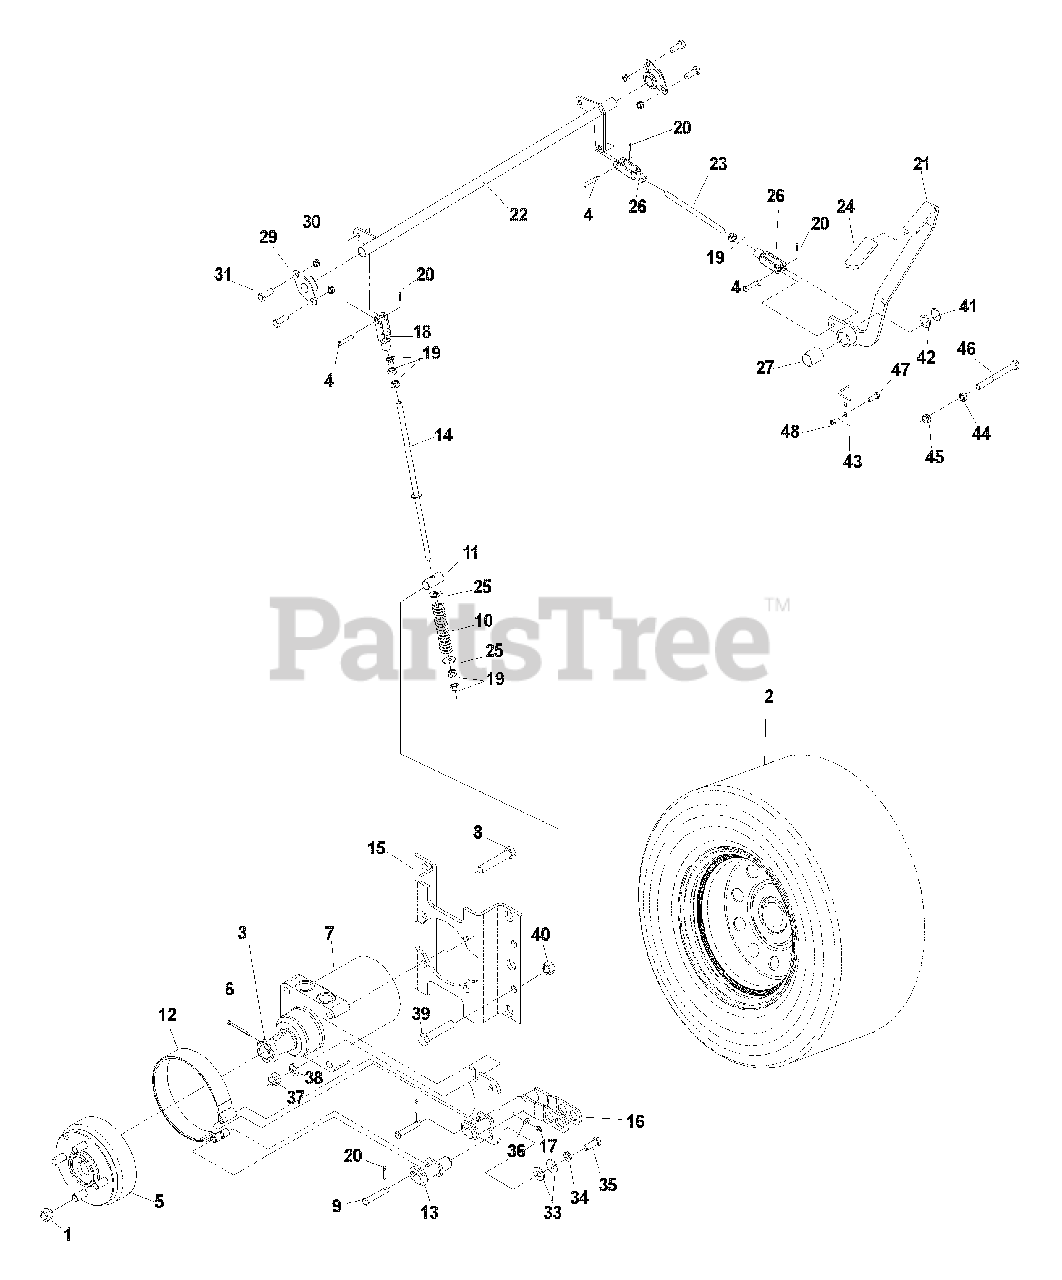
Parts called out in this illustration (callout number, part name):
1	LUG NUT 1/2F
2	REAR TIRE ASM. (COMPLETE)
2	TIRE, 23 X 10.5-12
2	RIM, 12 X 8.5
2	VALVE STEM
3	HEX SLOTTED NUT
4	CLEVIS PIN, 3/8 X 1 1/8
5	HUB, W/BRAKE DRUM
6	KEY-COTTER, 4 MM X 45 MM
7	WHEEL MOTOR
8	HCS 1/2C X 2 3/4
9	PIN-CLEVIS, 3/8 X 2
10	SPRING-BRAKE COMPRESSION
11	PIN-TRUNION
12	BAND-BRAKE
13	BRAKE BAND SUPPORT
15	MOTOR STANDOFF
16	BRAKE WLDMT
17	ZERK, STRAIGHT, 1/4-28
18	YOKE, 3/8-24
19	NUT, HEX, 3/8F
20	PIN-COTTER, 1/8 X 3/4
21	BRAKE LEVER WLDMT
22	BRAKE CROSS SHAFT
23	LINKAGE SHORT
25	WASHER, 7/16
29	FLANGE BEARING
30	NUT, 3/8C, NYLOC
31	HCS 3/8C X 1
32	COTTER PIN
33	WASHER 3/8, FLAT
34	LOCKWASHER, 3/8
35	HCS 3/8C X 1, GD 8
38	LOCKWASHER, 1/2
39	HCS 1/2 X 1 1/4, SERR WASHER
40	NUT, 1/2C, NYLOC
41	RING, 7/8, RET.
42	BUSHING, MACH.
44	NUT, 3/8C, WHIZ
45	NUT, 3/8C, NYLOC
46	HCS, 3/8C X 2 1/2
47	HCS, 1/4C X 3/4
48	NUT, 1/4C, NYLOC
